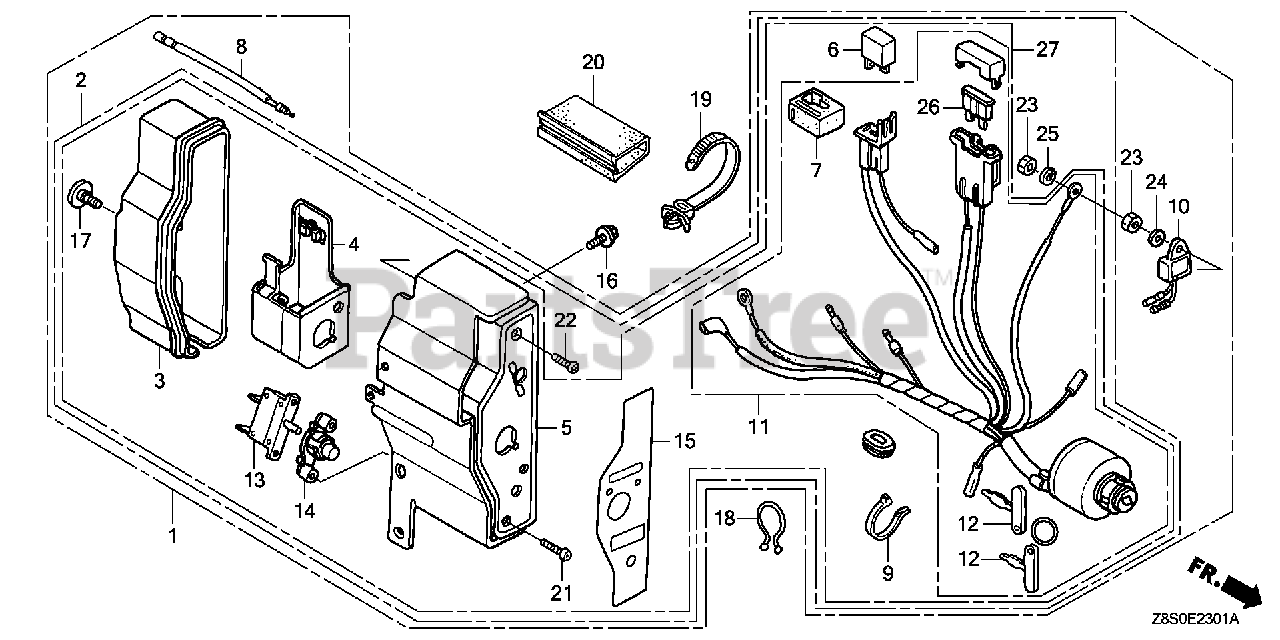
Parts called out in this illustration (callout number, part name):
3	CASE, CONTROL
4	BRACKET, CASE MOUNTING
5	PANEL, CONTROL *NH1* (BLACK)
5	PANEL, CONTROL *R280* (POWER RED)
6	RECTIFIER ASSY., SILICON (SHINDENGEN)
7	SUSPENSION, CONNECTOR
9	BAND
11	SWITCH ASSY., COMBINATION (3A-CHARGE)
12	KEY
13	PROTECTOR, CIRCUIT (3.5A)
14	LENS ASSY., PROTECTOR
15	MARK, CONTROL BOX (EXTERNAL)
16	BOLT, FLANGE (6X12) (CT200)
17	SCREW, SPECIAL (6X12)
18	CLIP, PURSE LOCK
19	STRAP, CABLE (118MM) *NH1L* (Honda Code 1170653). (BLACK)
20	TUBE, FASTENER (30)
21	SCREW, PAN (3X12)
26	FUSE, BLADE (5A)
26	FUSE, BLADE (15A)
27	BOX ASSY., CONTROL (3A) *NH1* (EXP-ALERT) (BLACK)
27	BOX ASSY., CONTROL (3A) *R280* (EXP-ALERT) (POWER RED)
